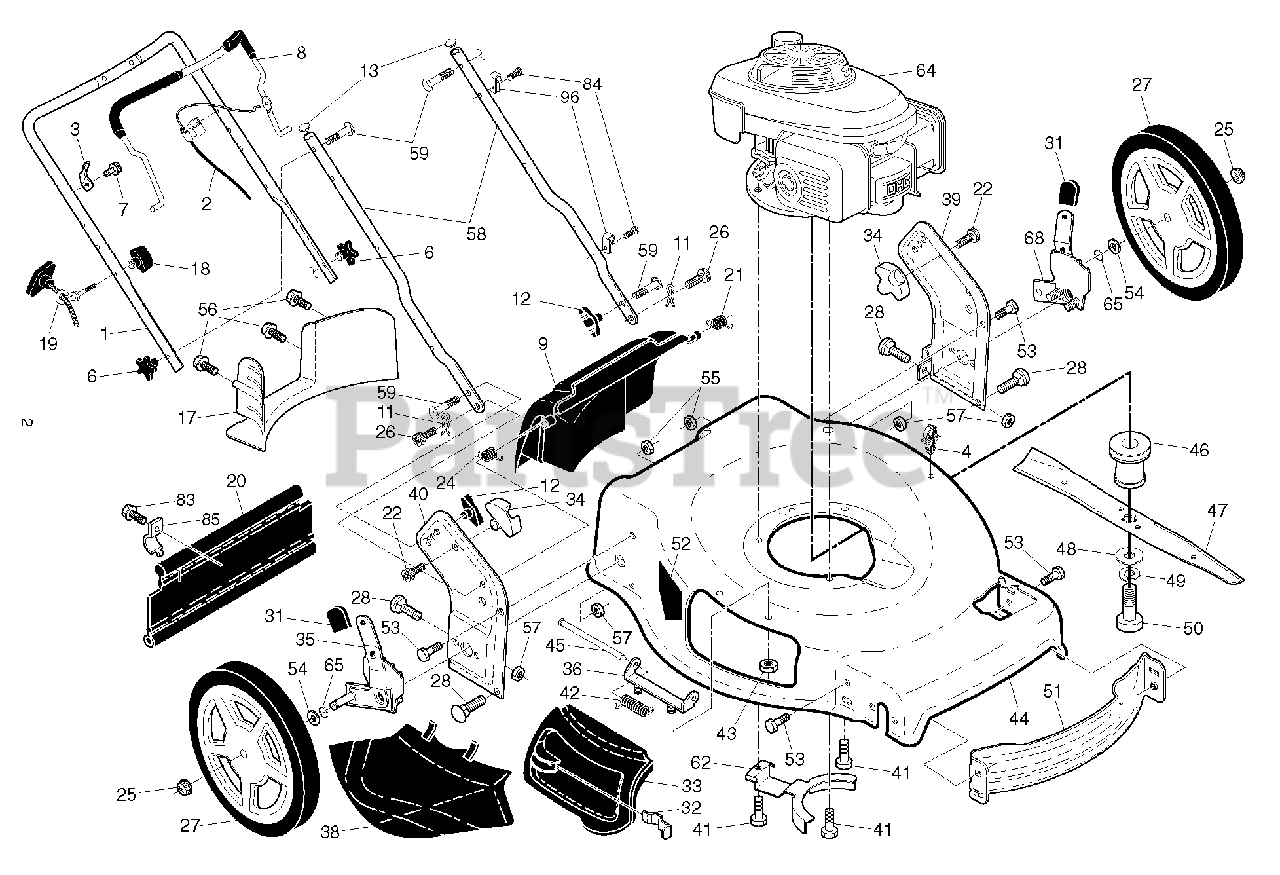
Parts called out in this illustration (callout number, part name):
1	HANDLE.UP.3POS.BS.AW2.479
2	CABLE.ASM.ZONE.CONTROL
3	BRACKET.UPSTOP.RT
4	PUSH CLIP
6	KNOB.HANDLE.PLASTIC.STAR.BLACK
8	BAIL.OM.ERGO.MZR.BLK.428
11	COTTER.HAIRPIN.DOOR/HANDLE.PIV
12	KNOB, DEFLECTOR
13	PLUG.PLASTIC.7/8".14-20.GAUGE
18	T-Knob, New Rope Guide
19	Rope Guide, Blk Zinc Chrom
20	SKIRT.REAR.22PLUS.RGD/FGD.NEW
21	SPRING.LH.GRAY
22	SCREW.PAN.HEAD.#10
24	SPRING.RH.GRAY
25	NUT.HEX.FLANGE.3/8-16.LOCKNUT
26	SCREW,DOOR/HANDLE.PIVOT
27	Wheel, 12 X 1.75 5-Spoke White
28	Carriage Bolt, 5/16-18 X 5/8
31	SELECTOR KNOB
32	LATCH.DOOR.ZINC
34	BRACKET.GRASSBAG.ATTACHING.BLK
35	ADJUSTER.ASM.9POS.HW.R/R
36	HINGE BRACKET ASSEMBLY
38	DEFLECTOR.CLIPPING.22.BLACK
39	Handle Bracket Assembly, LH 22+ Black
40	Handle Bracket Assembly, RH 22+ Black
41	BOLT 3/8-16X1-1/8
42	SPRING.TORSION
43	NUT.HEX.FLANGE.1/4
45	ROD.HINGE.21
46	Blade Adapter, 25mm Star
47	BLADE.22+4N1.2PIN.5STAR.
48	WASHER,HARDEN
49	LOCKWASHER
50	SCREW, HEX HD 3/8-24 X 1-3/8
52	DANGER DECAL
53	BOLT.5/16HEX.WHS.HD
54	WASHER PM
55	NUT.HEX.FLANGE.1/4
56	SCREW.HX.13X.750
57	NUT.FLANGE.5/16
58	HANDLE.LOWER.22+.BT.2PC.BLK
59	BOLT, HANDLE 5/16-18X1.75
62	BRACKET.ENG/BELTKEEPER
65	O-RING..070X.487.NEOPRENE
68	ADJUSTER.ASM.9POS.HW.R/L
83	TAPPING SCREW
84	FASTENER.PUSH.O.250X0.783
85	BRACKET.SKIRT.22+.BZP
96	CLIP.CABLE.BLK
